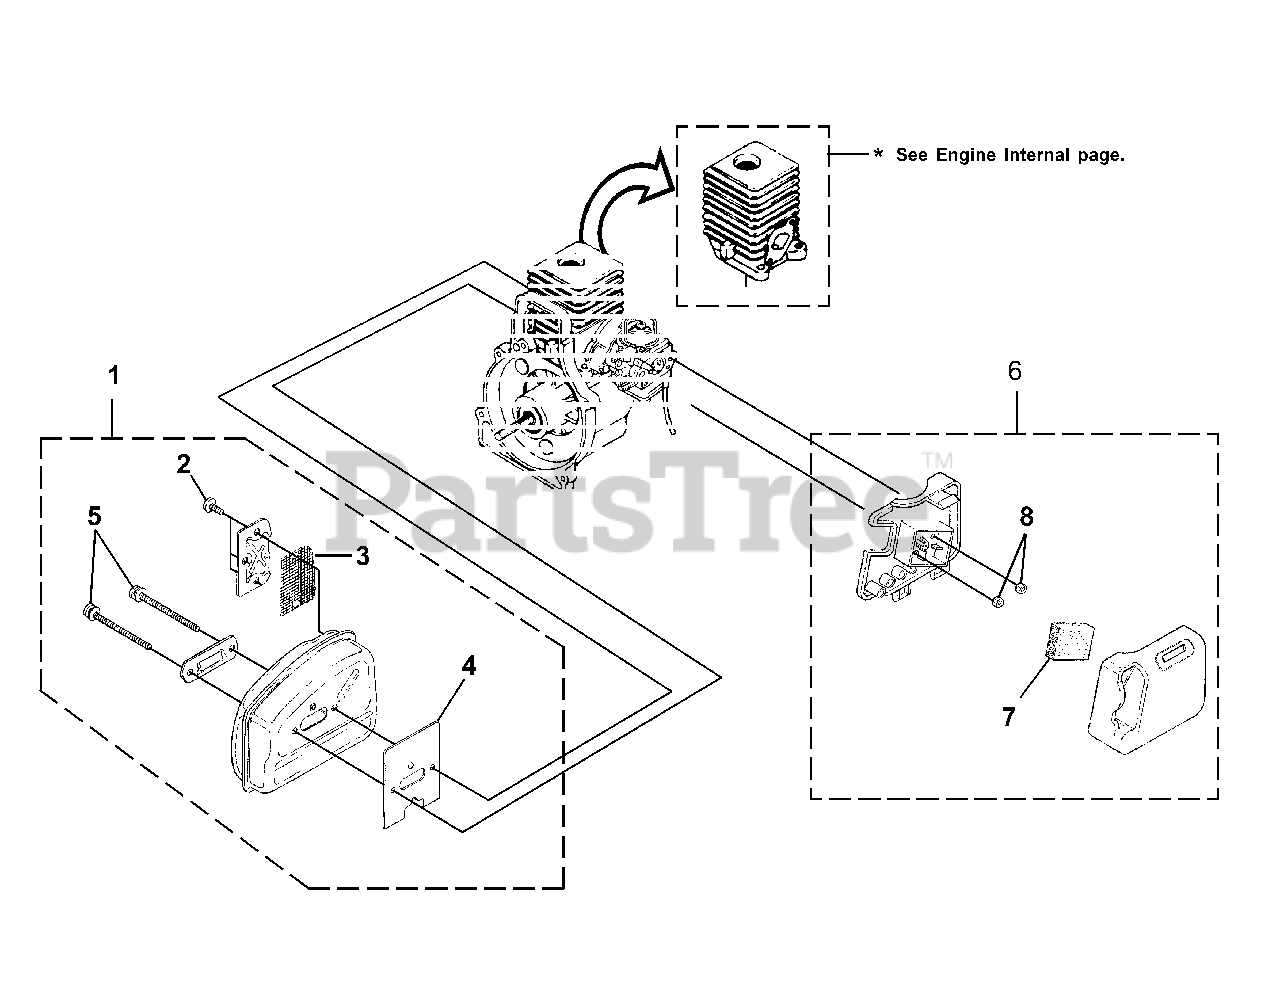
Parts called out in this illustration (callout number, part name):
1	MUFFLER ASSY.
2	SCREW, Taptite- (8-32 X 3/8")
3	SCREEN-Spark
4	GASKET-Muffler
5	SCREW, Truss Hd. - (10-24 X 2.188)
6	AIR FILTER KIT
7	FILTER-AIR
8	NUT-Hex (10-24)
